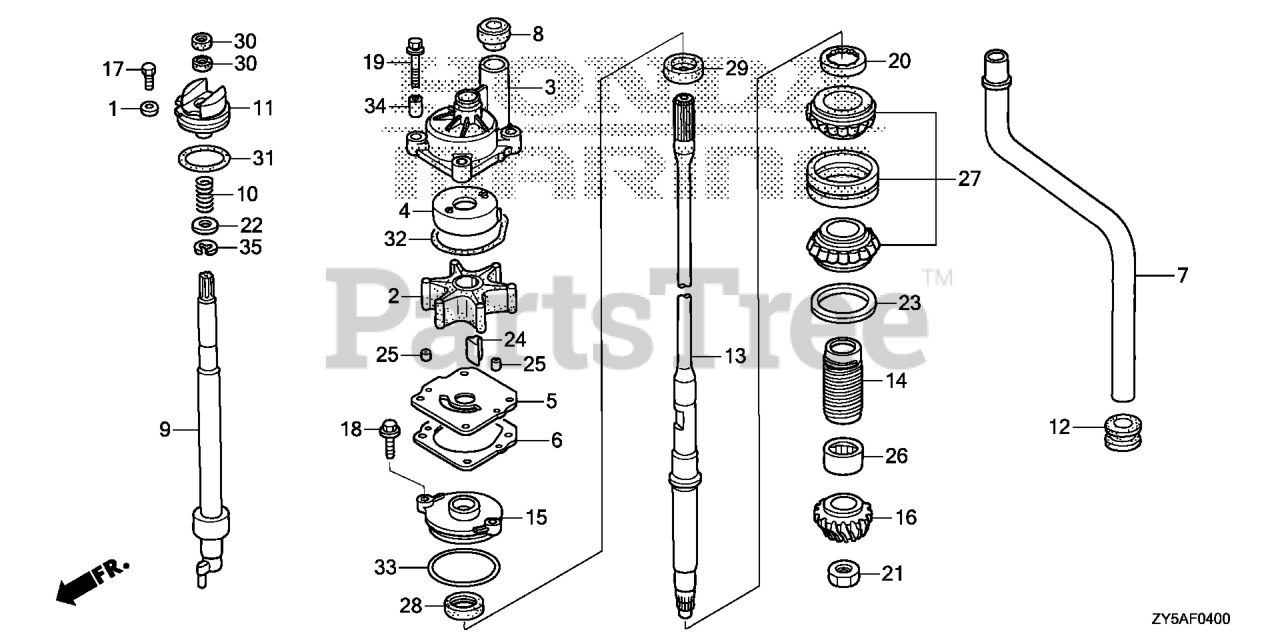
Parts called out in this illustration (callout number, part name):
1	WASHER, PIVOT
2	IMPELLER, PUMP
3	HOUSING, IMPELLER
4	LINER, PUMP
5	COVER, IMPELLER
6	GASKET B, IMPELLER
7	TUBE, WATER (XL)
8	RING, WATER TUBE SEAL
9	ROD, SHIFT (COUNTER ROTATION)
10	SPRING, SHIFT ROD
11	HOLDER, SHIFT ROD
12	GROMMET, EXTENSION CASE
13	SHAFT, VERTICAL (XL)
14	SLINGER, OIL
15	HOUSING, WATER SEAL
16	GEAR, PINION
17	BOLT, HEX. (6X12) Use up to Frame SN 1005248.
18	BOLT, FLANGE (6X20) (ENGINE NO.)
19	BOLT-WASHER (8X40)
20	NUT, LOCK (64MM)
21	NUT, HEX. (18MM)
22	WASHER, PLAIN (12MM)
23	SHIM A, GEAR (0.10)
23	SHIM B, GEAR (0.15)
23	SHIM C, GEAR (0.30)
23	SHIM D, GEAR (0.50)
24	KEY, WOODRUFF
25	PIN, DOWEL (6X10)
26	BEARING, NEEDLE (28.575X44.45X31.75)
27	BEARING, TAPER ROLLER (30X62X40)
28	SEAL, WATER (23X36X8)
29	SEAL, WATER (23X36X6)
30	SEAL, WATER (12X21X6)
31	O-RING (55.6X3.5)
32	O-RING, WATER PUMP
33	O-RING (58.5X3.5)
34	COLLAR, DISTANCE
35	E-RING (10MM)
